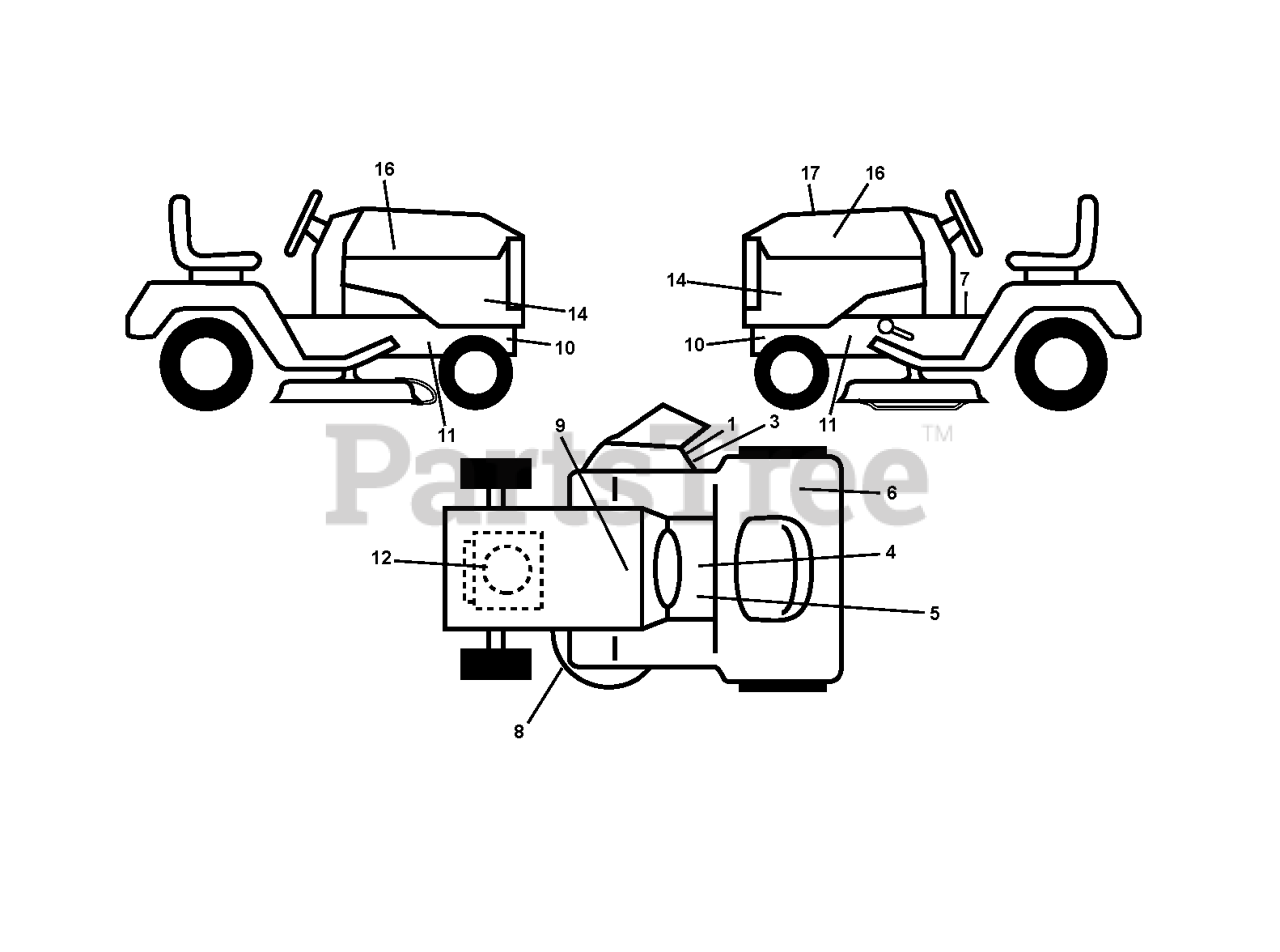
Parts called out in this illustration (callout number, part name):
1	DECAL.INTERNATIONL.CUTFINGER
3	DECAL, DEFLECT WARNING
4	DECAL PARK BRAKE
5	LABEL
6	Decal, Fender 100 DB/CE
7	DECAL
8	DECAL V BELT SCHEMATIC
9	DECAL BTRY SYMBOLS
12	DECAL
16	DECAL.HOOD.NAMELOGO.HUSQ
